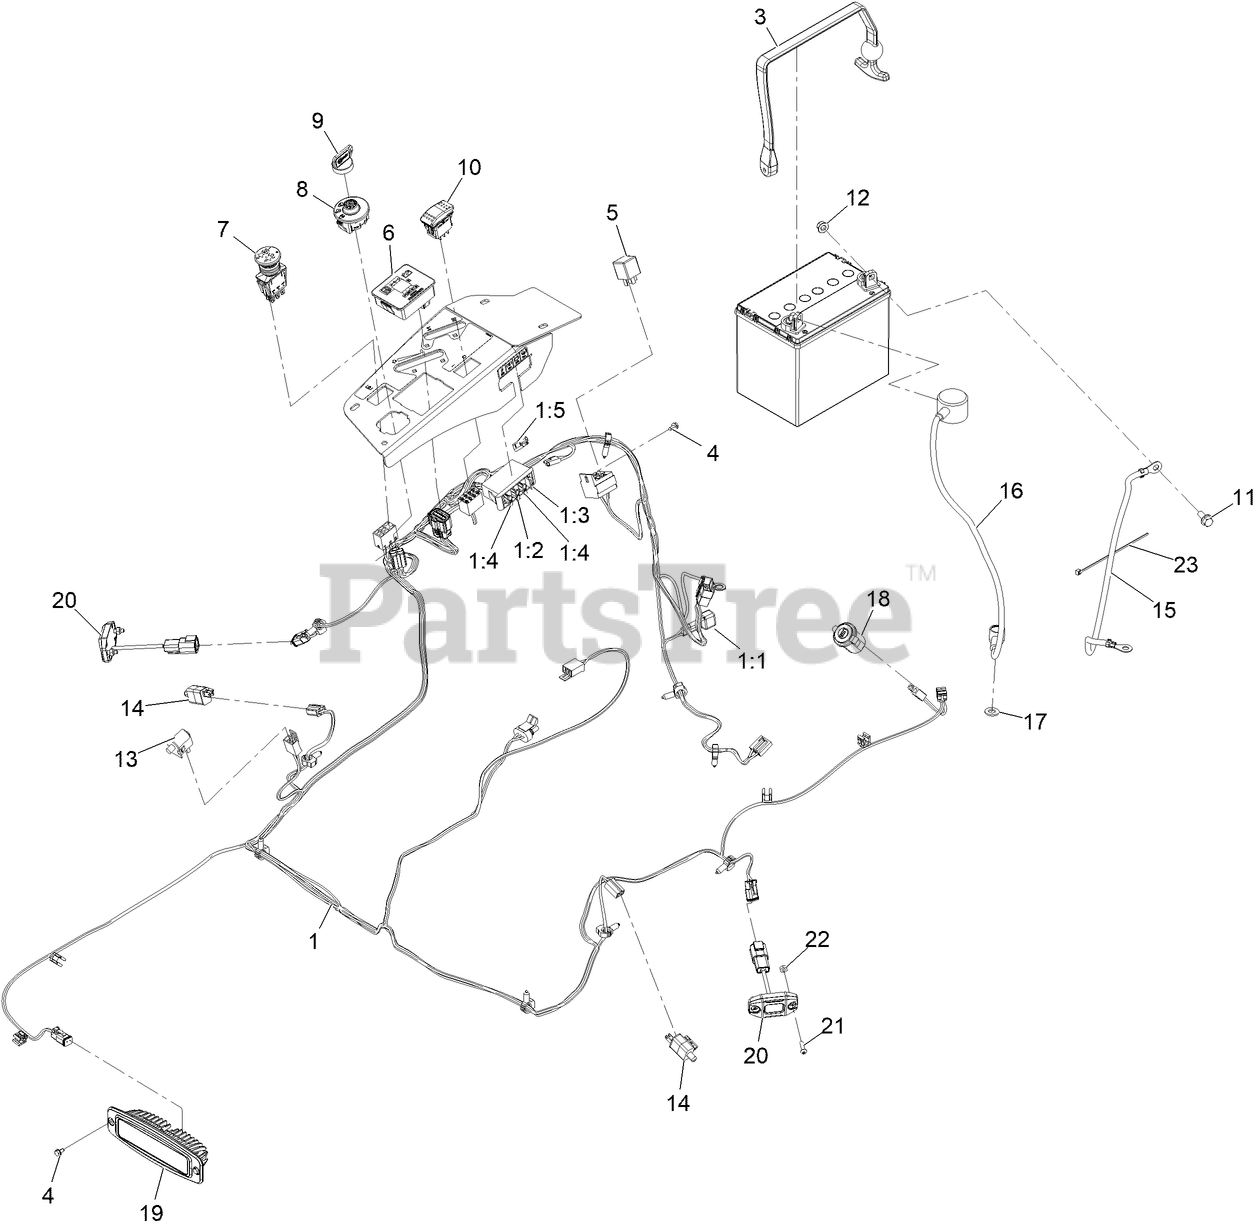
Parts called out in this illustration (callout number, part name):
1	HARNESS-MAIN LRX CARB
1:2	FUSE-BLADE, 10 AMP
1:3	FUSE-BLADE, 15 AMP
1:4	FUSE-BLADE, 25 AMP
1:5	CAP-PLUG
3	Strap-Bungee
4	SCREW-HWH
6	FUEL/HOUR METER ASM
7	SWITCH, PTO 10A
8	SWITCH-IGNITION
9	KEY-IGNITION
11	SCREW-HHF
12	NUT-HF, NI
13	SWITCH-BAIL
15	CABLE-BATTERY, NEGATIVE
16	CABLE-BATTERY, POSITIVE
17	WASHER-FLAT
18	PORT-POWER, USB
19	MOUNT-FLUSH, LIGHT
20	LIGHT-ROCK
21	Screw-HSBH
22	Nut-Speed
23	TIE-CABLE
